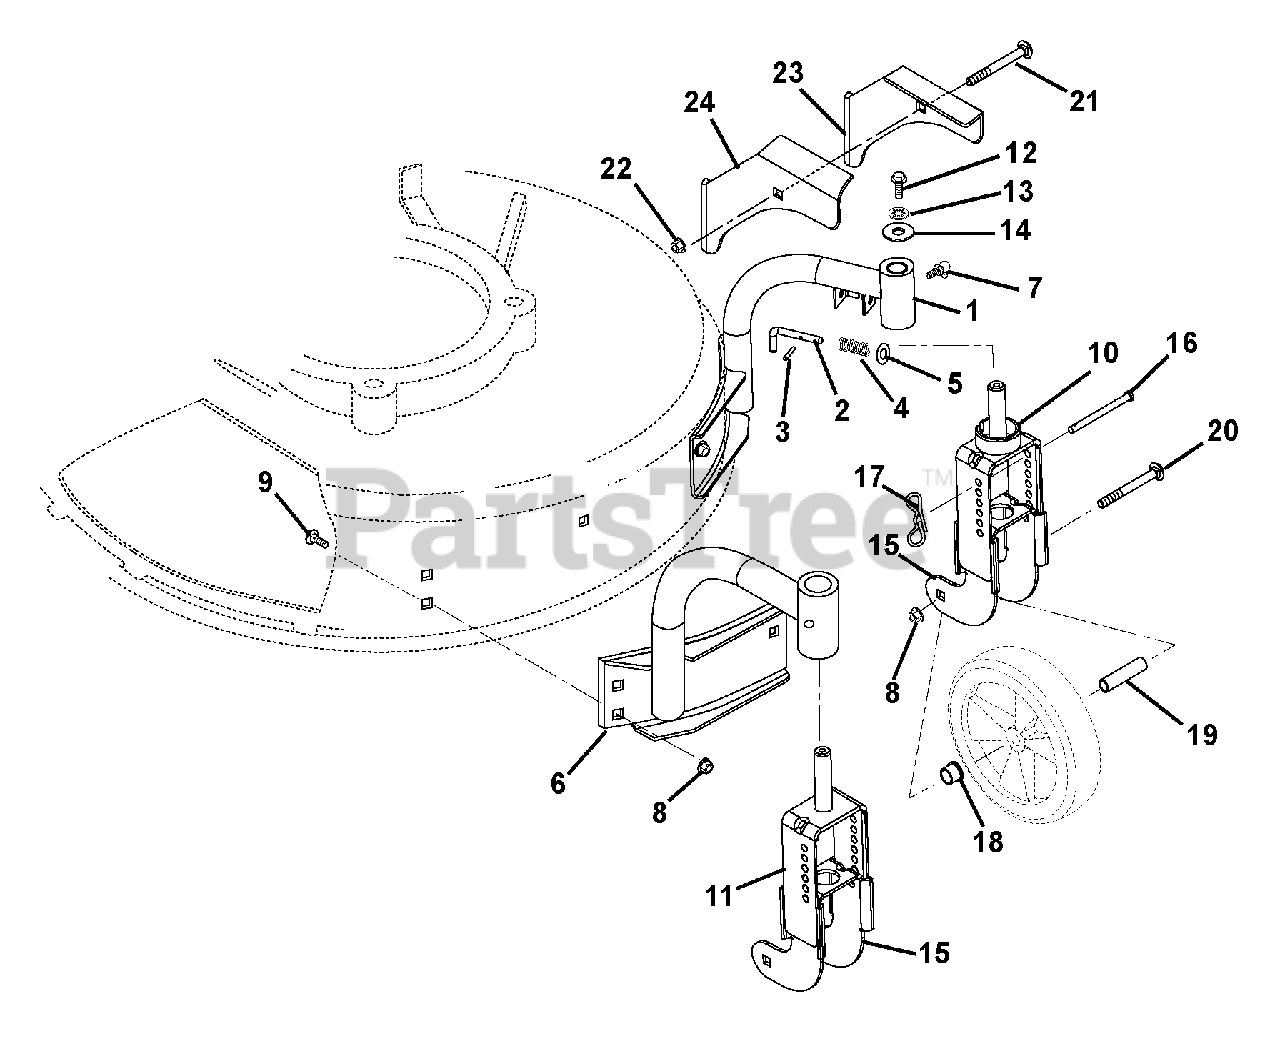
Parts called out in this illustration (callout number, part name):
1	ASSY, MOUNT LH W/BUSHINGS
2	PIN, LOCKOUT
3	PIN-ROLL .093X.50
4	SPRG, COMP--SWVL LOCKOUT
5	@WSHR-FL-STL.281X.62X.065 YWZC
6	ASSY, RH MOUNT W/BUSHINGS
7	FTG-LUBE .25-28X.256 YWZC
8	@NUT-SPNLK-FLG .312-18 YWZC
9	@BLT-RDHDSQNK .31-18X.50 G5YZ
10	YOKE, OUTER LH
11	YOKE, RH OUTER
12	@BLT-HEX .25-20X.75 GR5 YWZC
13	@WSHR-LK .25X.062 REG YWZC
14	WSHR-FL-STL .281X1.000X.063
15	YOKE-INNER
16	PIN, HEIGHT ADJUSTMENT
17	PIN, BOW TIE LOCKING COTTER
18	BSHG-FLG .500X.625X.500X.750
19	SPCR, WHEEL .385X.500X2.00
20	BLT-RDHDSQSHNK.31-18X2.75G2YWZ
21	@BLT-RDHDSQNK .25-20X1.50 G5YZ
22	@NUT-SPNLK-FLG .25-20 YWZC
23	BRACKET, HOOD CABLE--LH
24	BRACKET, HOOD CABLE WELDMENT
